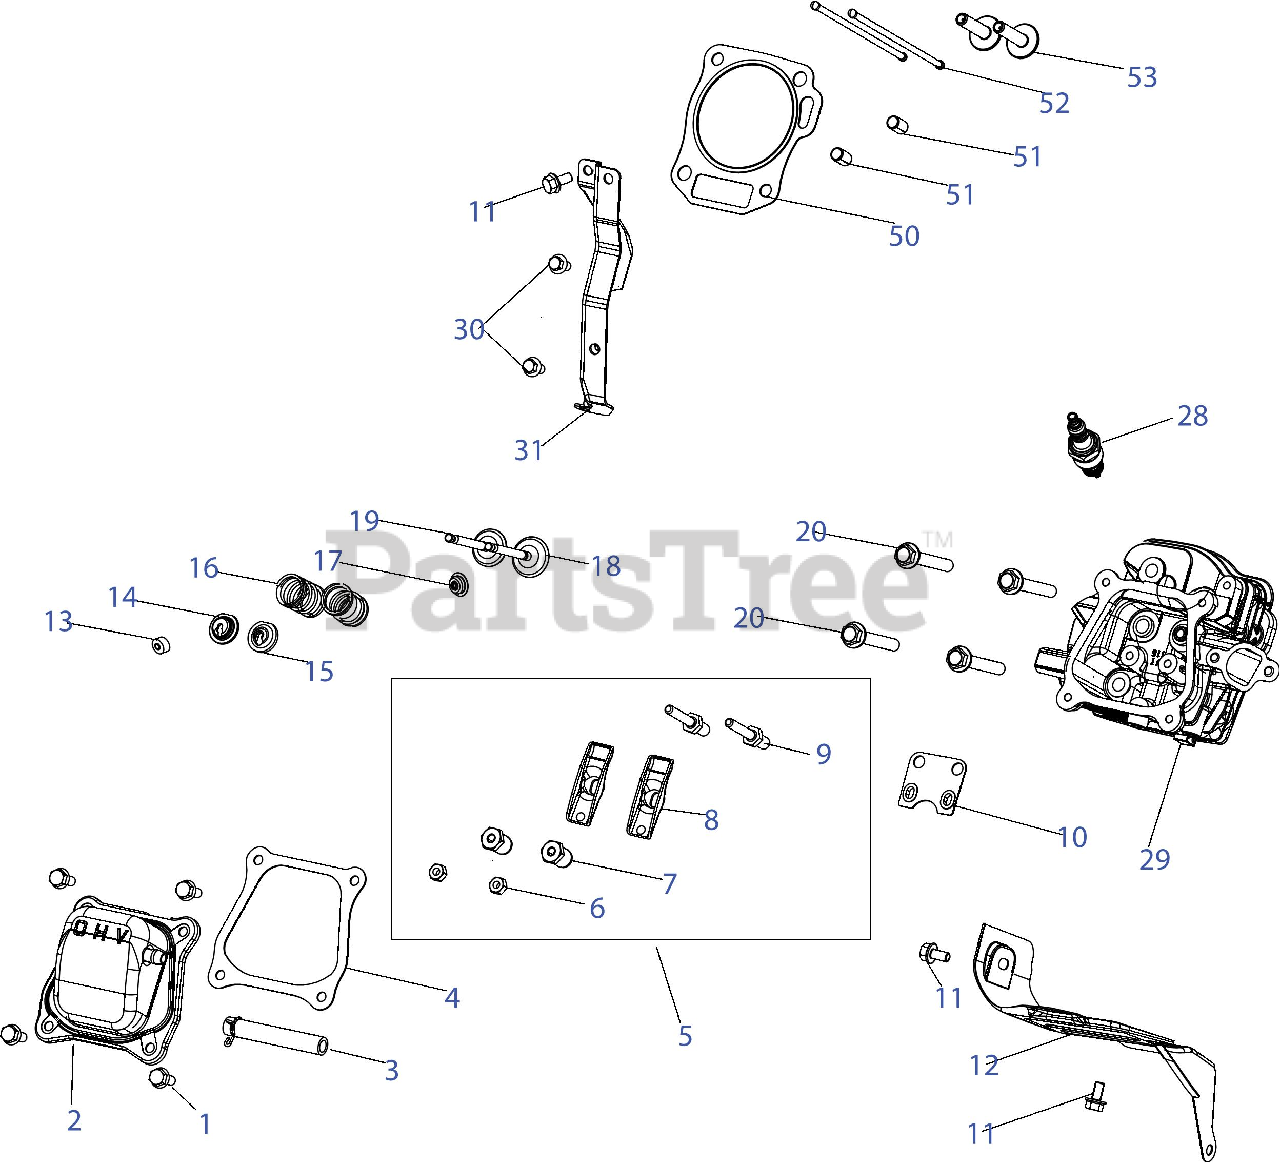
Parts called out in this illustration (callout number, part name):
1	Bolt, M6?16
2	Valve Cover
3	Breather Hose
4	Gasket, Valve Cover
5	Rocker Arm Assembly
6	Lock Nut
7	Adjust Nut
8	Rocker Arm
10	Rocker Arm Base
11	Bolt, M6?12
12	Shroud
13	Valve Adjust Cap, Exhaust
14	Valve Spring Seat
15	Valve Spring Seat
16	Valve Spring
17	Intake Valve Seal
18	Intake Vavle
19	Exhaust Valve
20	Bolt, M8?55
28	Spark Plug
29	Cylinder Head
30	Bolt, M6?12
31	Snow Guard
50	Gasket, Cylinder Head
51	Pin, 10?16
52	Push Rod
53	Tappet
